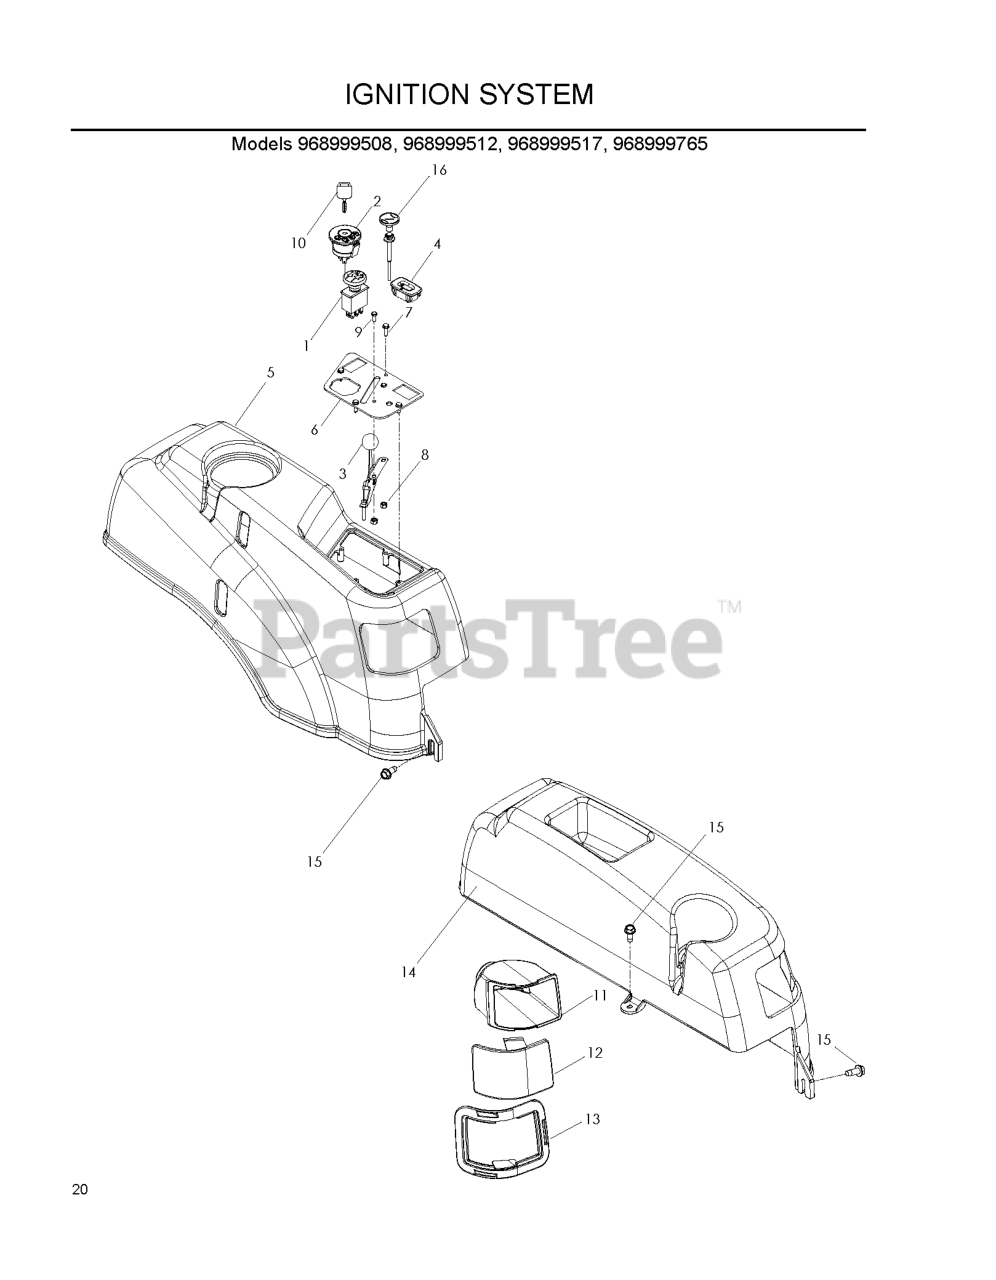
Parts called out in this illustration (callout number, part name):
1	RP.SWITCH, BLADE
2	RP IGNITION SWITCH
3	THROTTLE CABLE
4	HOUR METER
5	RP.FENDER, RT
6	CONSOLE.PLATE.BLACK
7	SCR #10-12X3/4 HEX WAS HD ZD
8	NUT 10-24 NYLOC
9	HCS #10-24 X 1/2
10	KEY
11	LEFT HEADLIGHT REFLECTOR
11	RT HEADLIGHT REFLECTOR
12	LENS, COLORED RIGHT
12	LENS, COLORED LEFT
13	LEFT HEADLIGHT RIM GREY
13	RT HEADLIGHT RIM GREY
14	FENDER, LT
15	SCREW 1/4 X 5/8
16	CHOKE CONTROL
